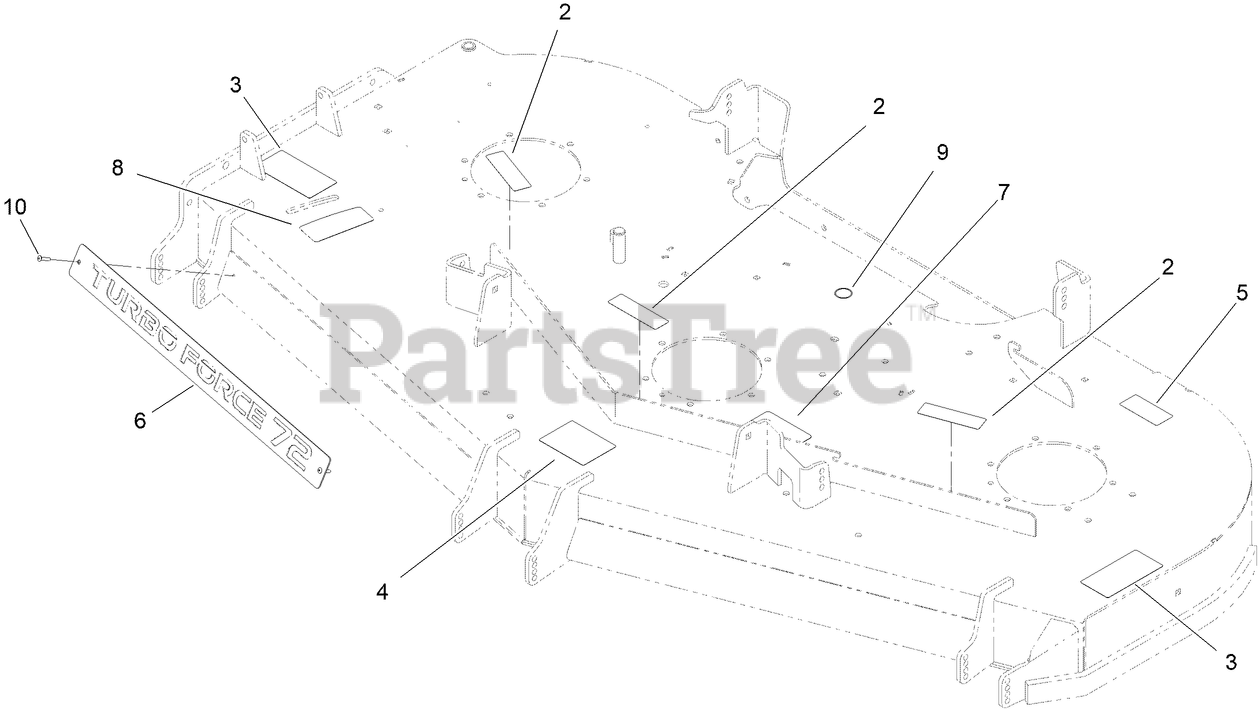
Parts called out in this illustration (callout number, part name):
2	DECAL-COVER, MISSING
3	DECAL-DANGER
4	DECAL-SCALP, ANTI
5	DECAL-BOLT TORQUE
6	PLATE-TURBO FORCE [BLACK]
7	DECAL-BELT ROUTING
8	DECAL - BAFFLE ADJUSTMENT
9	DECAL-GREASE
10	RIVET-TRIFOLD
